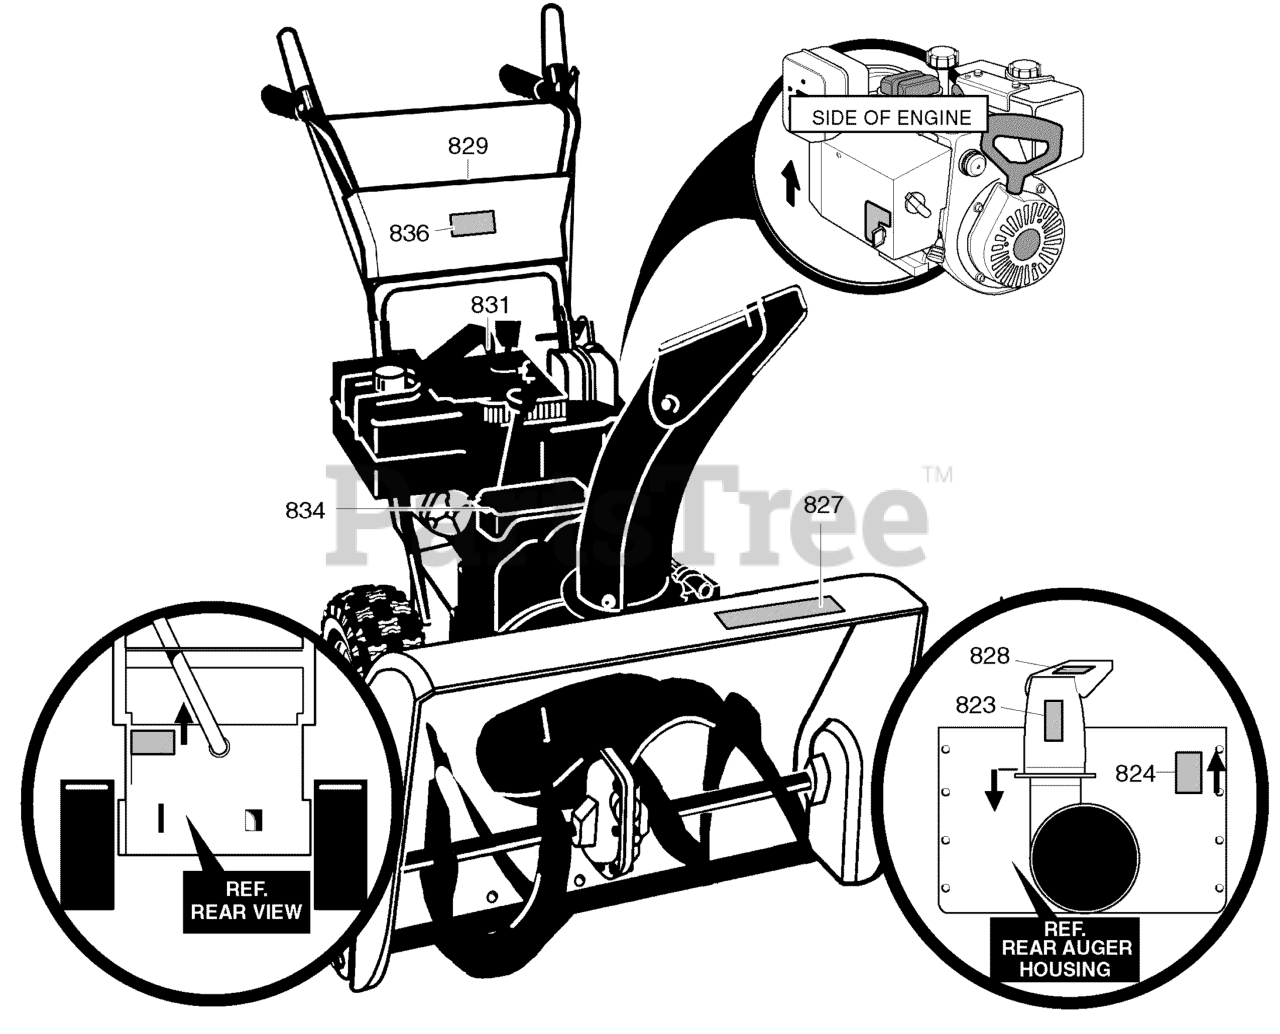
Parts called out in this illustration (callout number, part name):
823	DECAL, DANGER CHUTE HAND
824	DECAL, DANGER FOOT
827	DECAL, 5.5/22 CRAFTSMAN
828	DECAL, THROWN OBJECTS
829	DECAL, DRIVE/AUGER CLUTCH
831	DECAL, GEAR SELECTOR
834	DECAL, TOOLBOX INFORMATION
836	DECAL, CRAFTSMAN
